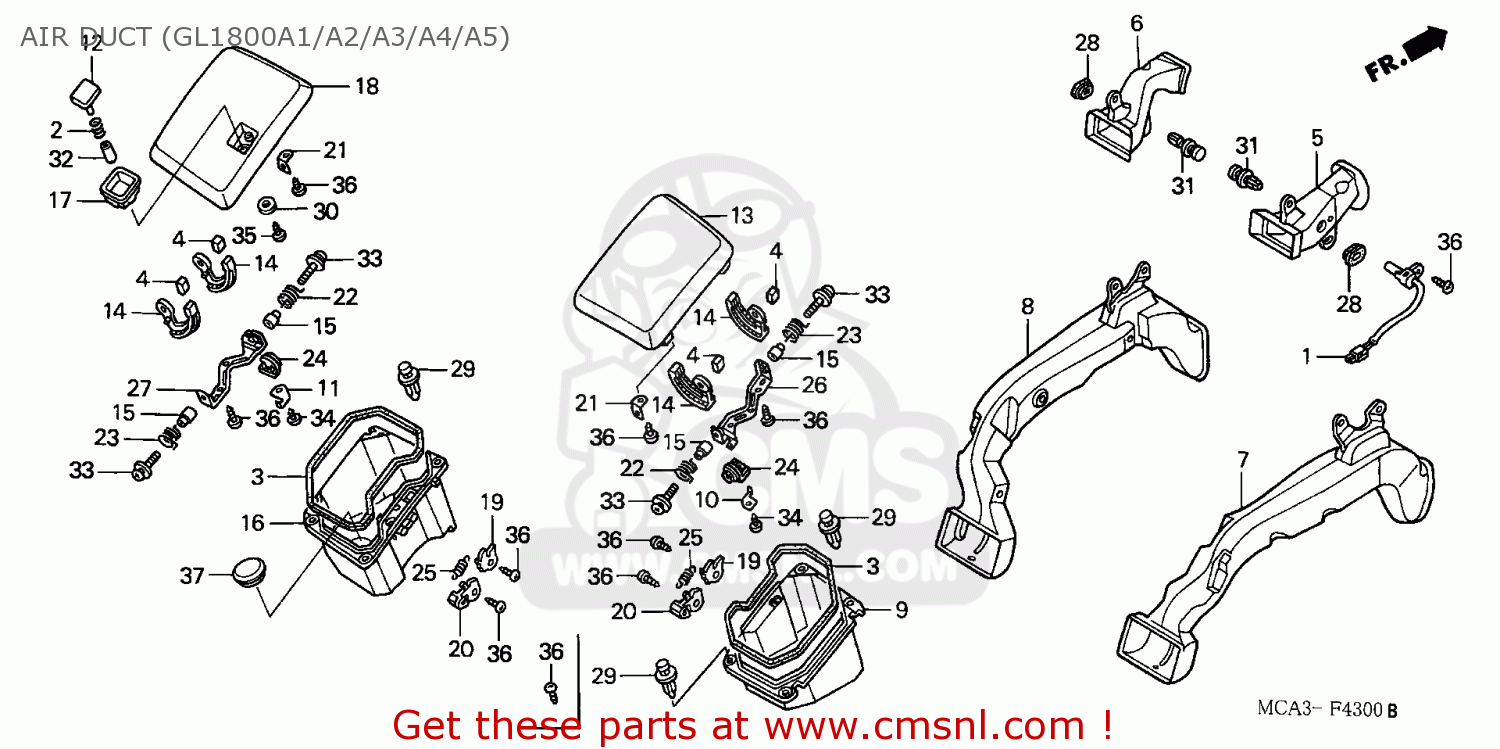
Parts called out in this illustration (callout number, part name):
1	OPEN AIR TEMPSENS
2	SPRING,COIL
3	SEAL,POCKET
4	SEAL,POCKET ARM
5	DUCT,R AIR UPPER
6	DUCT,L AIR UPPER
7	DUCT,R AIR LWR.
8	DUCT,L AIR LWR.
9	POCKET,R FRONT
10	PLATE,R POCKET AR
11	PLATE,L POCKET AR
12	BUTTON,L POCKET C
13	COVER,R POCKET
14	ARM,FR POCKET
15	COLLAR,POCKET ARM
16	POCKET,L FRONT
17	COVER,L BUTTON
18	COVER,L POCKET
19	CAM A,POCKETCOVER
20	CAM B,POCKETCOVER
21	PLATE,POCKET LOCK
22	SPRING,A FRONT PO
23	SPRING,B FRONT PO
24	DAMPER,FRONT POCK
25	SPG,POCKET LOCK C
26	STAY,R POCKETCOVE
27	STAY,L POCKETCOVE
28	GROMMET,A/C.CASE
29	CLIP,BPR SEAL
30	WASHER PLAIN 3MM
31	CLIP,PANEL F*NH1*
32	COLLAR A
33	SCREW-WASH.,4X25
34	SCREW,TAPPING,3X1
35	SCREW,TAP.,3X12
36	SCREW,TAPPING,4X10
37	GROM WASHER HOLE
